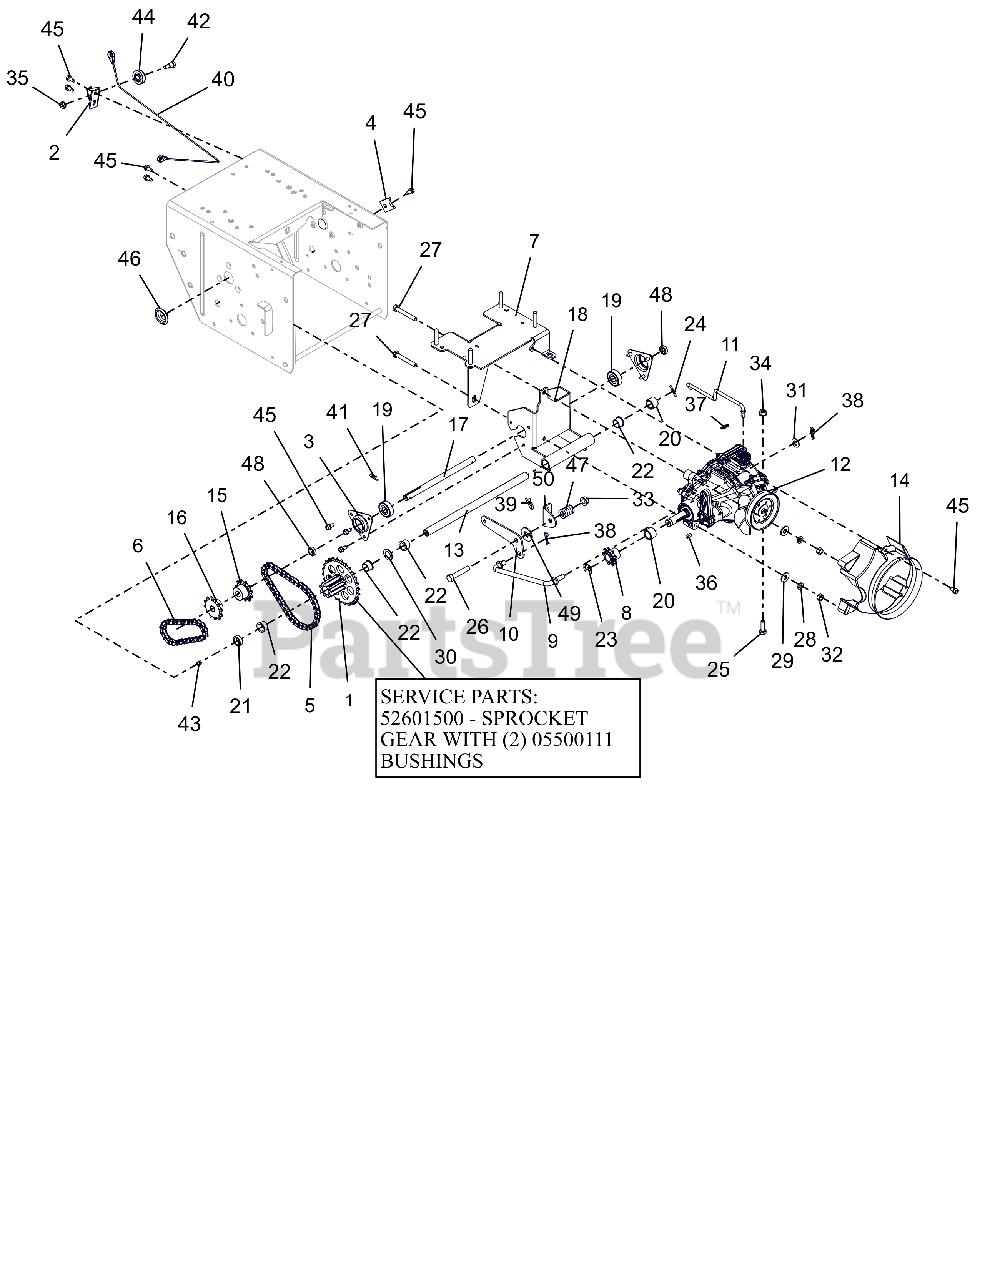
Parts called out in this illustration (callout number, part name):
1	PINION & SPROCKET
1	PINION & SPROCKET W/BUSHINGS
2	BRACKET, CABLE PULLEY
3	FLANGE, BEARING
4	TAB, ANTI ROTATION
5	ROLLER CHAIN #41 - 34 PITCHES
6	CHAIN-ROLLER #41X26 PITCHES
7	BRACKET, HYDROSTATIC TRANS XLG
8	SPROCKET, PINION 9T W/KEY
9	ROD, HYDRO TRANS SHIFT
10	PIVOT, HYDRO TRANS SHIFT
11	ROD, HYDRO BYPASS
12	TRANSMISSION, HYDROSTATIC
13	SHAFT, PINION - HARDENED
14	SHROUD, HYDROGEAR RT-310
15	SPROCKET, 11 TOOTH
16	SPROCKET, 12 TOOTH
17	SHAFT, REDUCTION HEAT TREATED
18	SUPPORT, REDUCTION-BWT
19	BRG-BALL .500X1.38X.437
20	SPACER, .635X.880X.611
21	BSHG-SLV, .635X.880X.305
22	BSHG-FLG .625X.750X.500X.875
23	RG-RTNG-EXT .625X.042
24	@PIN-GRV .125X1.00 TP E ALLOY
25	BLT,HEX .31-18X1.00 G5 ZCC
26	BLT,HEX .38-16X2.00 G5 ZCC
27	BLT, HEX .31-18X2.25 G5 ZCC
28	WSHR, LK-HVY .312X.097 ZCC
29	WSHR,FLT .375X.875X.083 ZCC
30	WSHR, FLT .630X1.005X.062 ZCC
31	WSHR,FLT .406X.812X.065 ZCC
32	NUT, HEX .312-18 ZCC
33	NUT-LK-TOP-FLG .38-16 ZC120
34	NUT-LK-TOP-FLG .312-18 GF ZCC
35	NUT-LK-TOP-FLG .250-20 GF ZCC
36	KEY-SQ .187 X .50 X .187
37	PIN, HAIR #178 .06X.77 ZCC
38	PIN, HAIR #213 .08X1.19 ZCC
39	PIN, SPRING CLIP
40	CABLE, TRACTION, HYDRO PRO
41	CLIP, SPRING
42	BOLT, SHLDR -.375 X .375 X .25-20
43	ZERK,FITTING .25X.125 DRIVE IN
44	PULLEY, CABLE
45	SCR-TAP .25-20X.50 HWH ZCC
46	PLUG, HOLE - 1.125"
47	SG-COMP .187X.56X1.62
48	SPCR, SLV
49	FRICTION WASHER
50	BRACKET, HYDRO SHIFT PIVOT
